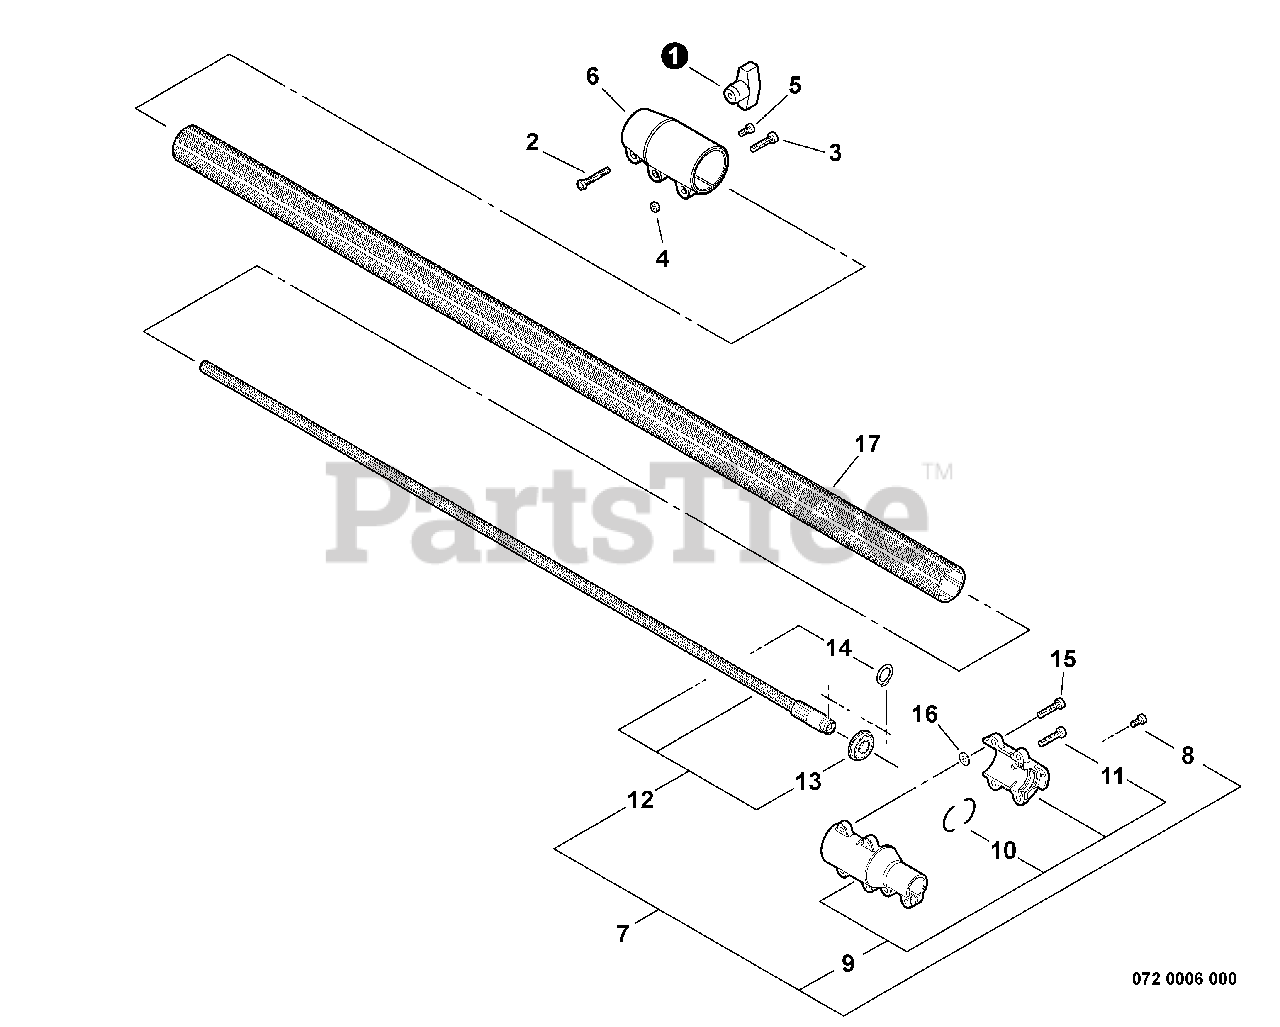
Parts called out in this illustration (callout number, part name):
1	THUMBSCREW
2	BOLT 6×25
3	BOLT 5×20
4	NUT M5
5	BOLT 5×12
6	COUPLING
7	COUPLING/DRIVESHAFT KIT
8	BOLT 5×14
9	COUPLING ASSY, LOWER
10	CUSHION
11	BOLT 5×20
12	DRIVESHAFT ASSY, LOWER
13	BEARING, BALL 15×32×9
14	RING, RETAINING
15	BOLT 5×20
16	WASHER 5
17	PIPE, MAIN - ORANGE
